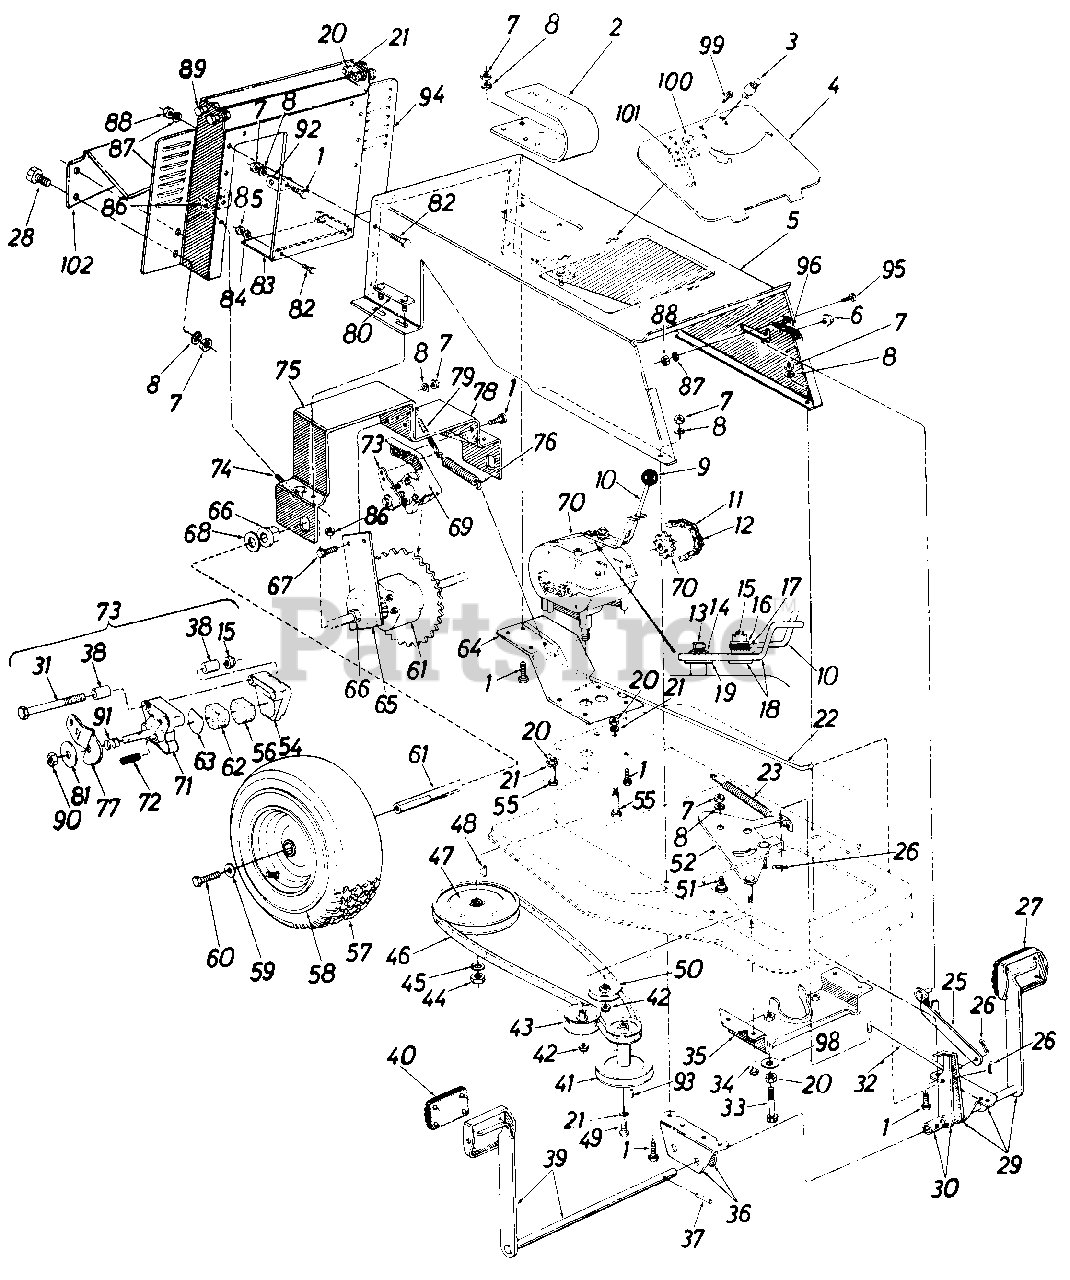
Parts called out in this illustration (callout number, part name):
1	Hex Sems Scr. 5/16-18 x .75" Lg.*
2	Seat Spring 3.25" High
3	Fastener
4	Rear Frame Cover
5	Rear Frame
6	Push Cap .25" Dia.-Black
7	Hex Nut 5/16-18 Thd.*
8	L-Wash. 5/16" Scr.*
9	Ball Knob
10	Shift Lever-Transmission
11	#420 Chain 1/2" Pitch x 77 Li n ks
12	#420 Master Link
13	Hex Scr. 1/4-28 x .62" Lg. (Lock)
14	Bell. Wash. .25" I.D. x .88 O.D. x .062
15	Hex Cent. L-Nut 5/16-18 Thd.
16	Fl-Wash. .344 I.D. x .88 O.D.
17	Rubber Wash. .33 I.D. x .87
18	Shift Lever Brkt. Ass'y.
19	Hardened Wash. 1.00 O.D.
20	Hex Nut 3/8-16 Thd.*
21	L-Wash. 3/8" Scr.*
22	Brake Rod
23	Extension Spring
25	Clutch Lockout Ass'y.
26	Cotter Pin 3/32" Dia. x .75"*
27	Clutch Pedal Pad
28	Hex Bolt 5/16-18 x .75" Lg.*
29	Clutch Pedal & Brkt. Ass'y.
30	Brake Lever Ass'y.
31	Hex Scr. 5/16-18 x 2.50" Lg.
32	Clutch Rod
33	Hex Scr. 3/8-16 x 3.5" Lg.
34	Hex Sems Scr. '/4-20 x .75"
35	Engine Belt Guard Ass'y.
36	Pedal "U" Brkt.-R.H.
37	Spring Pin Spiral .25" Dia. x 1.50" Lg.
38	Bushing
39	Brake Pedal Shaft Ass'y.
40	Brake Pedal Pad
41	Two-Step Engine Pulley
42	Hex Ins. L-Nut 3/8-24 Thd.
43	Fl-Idler w/Flanges 2.75" Dia.
44	Hex Jam Nut 1/2-20 Thd.*
45	L-Wash. 1/2" Scr.*
46	"V"-Belt 1/2" x 62" Lg.
47	Transmission Split Pulley .50" I.D.
48	#4 Hi-Pro Key 3/32 x 5/8" Dia.
49	Hex Scr. 3/8-24 x .75" Lg.*
50	"V"-Idler
51	Shld. Scr. .437" Dia. x .180
52	Idler Brkt. Ass'y.
54	Casting-Carrier
55	Shld. Scr. 498" Dia. x 2.00"
56	Pad-Friction
57	Rear Wheel Ass'y.-Comp. 14.5 x 4.5
58	Rear Wheel Rim Only
59	Bell. Wash. .345 I.D. x .88
60	Hex Cent. Lock Scr. 5/16-24 x .75" Lg. H.T.
61	Differential Ass'y. Comp.
62	Pad-Friction
63	Disc-Back-Up
64	Seat Support Ass'y.
65	Rear Axle Plate
66	Flange Brg. w/Flats .753 I. D.
67	Hex Sems Scr. 5/16-18 x 1.00" Lg.
68	Fl-Wash. .812 I.D. x 1.38" O.D. x .100
69	Disc Brake Brkt. Ass'y.
70	Transmission
71	Casting-Cam
72	Push Pin
73	Disc Brake Ass'y.-Comp.
74	Chain Adj. Link 5/16-18 x 4.38" Lg.
75	Rear Axle Brkt.-R.H.
76	Brake Spring
77	Cam Lever
78	Rear Axle Brkt.-L.H.
79	Brake Return Spring
80	Plate Ass'y. Axle Bolt
81	Washer
82	Truss Hd. Mach. Scr. 10-24 x.62" Lg.
83	Baffle Plate
84	Ext. L-Wash.
85	Hex Nut 1024 Thd.*
86	Hex Ins. L-Nut 5/16-18 Thd.
87	L-Wash. '/4" Scr.
88	Hex Nut 1/4-20 Thd.
89	Shld. Scr. .498 Dia. x .330
90	Hex Top L-Nut
92	Chute Pivot Brkt.
93	#6 Hi-Pro Key 5/32 x 5/8" Dia.
94	Grass Catcher Adapter
95	Hex Scr. 1/4-20 x .50" Lg.
96	Safety Switch
98	Belleville Washer
99	Hex Wash. Hd. Scr. #8 x .50"
100	Insulator Nut Plate
101	Spring Switch
102	Rear Chute Baffle
